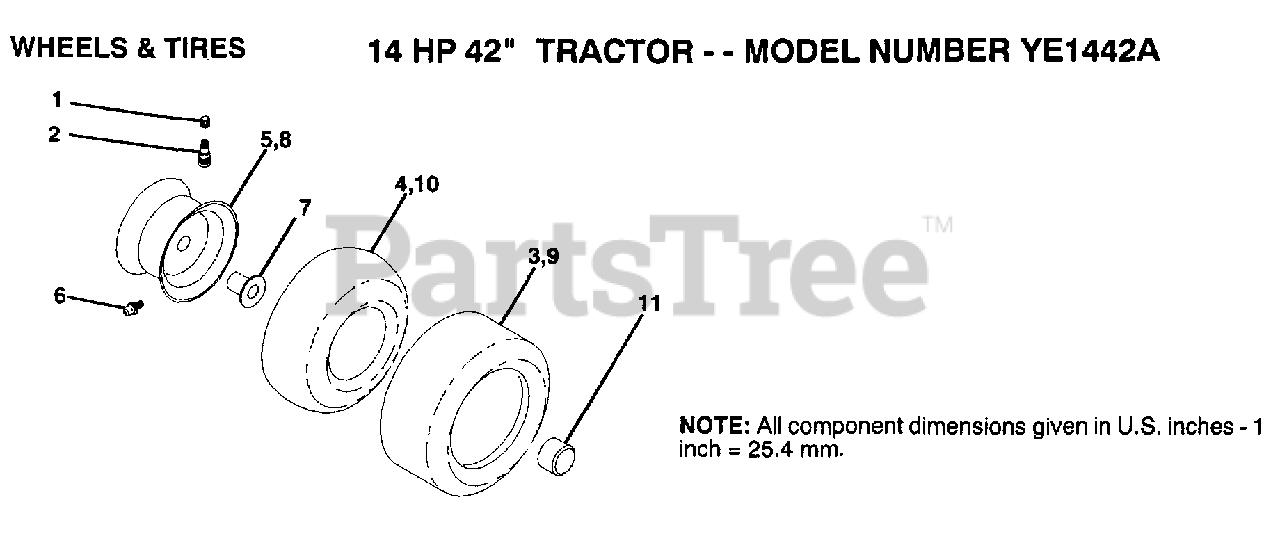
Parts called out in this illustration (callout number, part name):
1	VALVE CAP
2	VALVE STEM LT
4	TUBE.5.3/4.5/6
6	FITTING LT
7	"FLANGE, BEARING"
10	TUBE.18X9.5-8
11	HUB CAP
